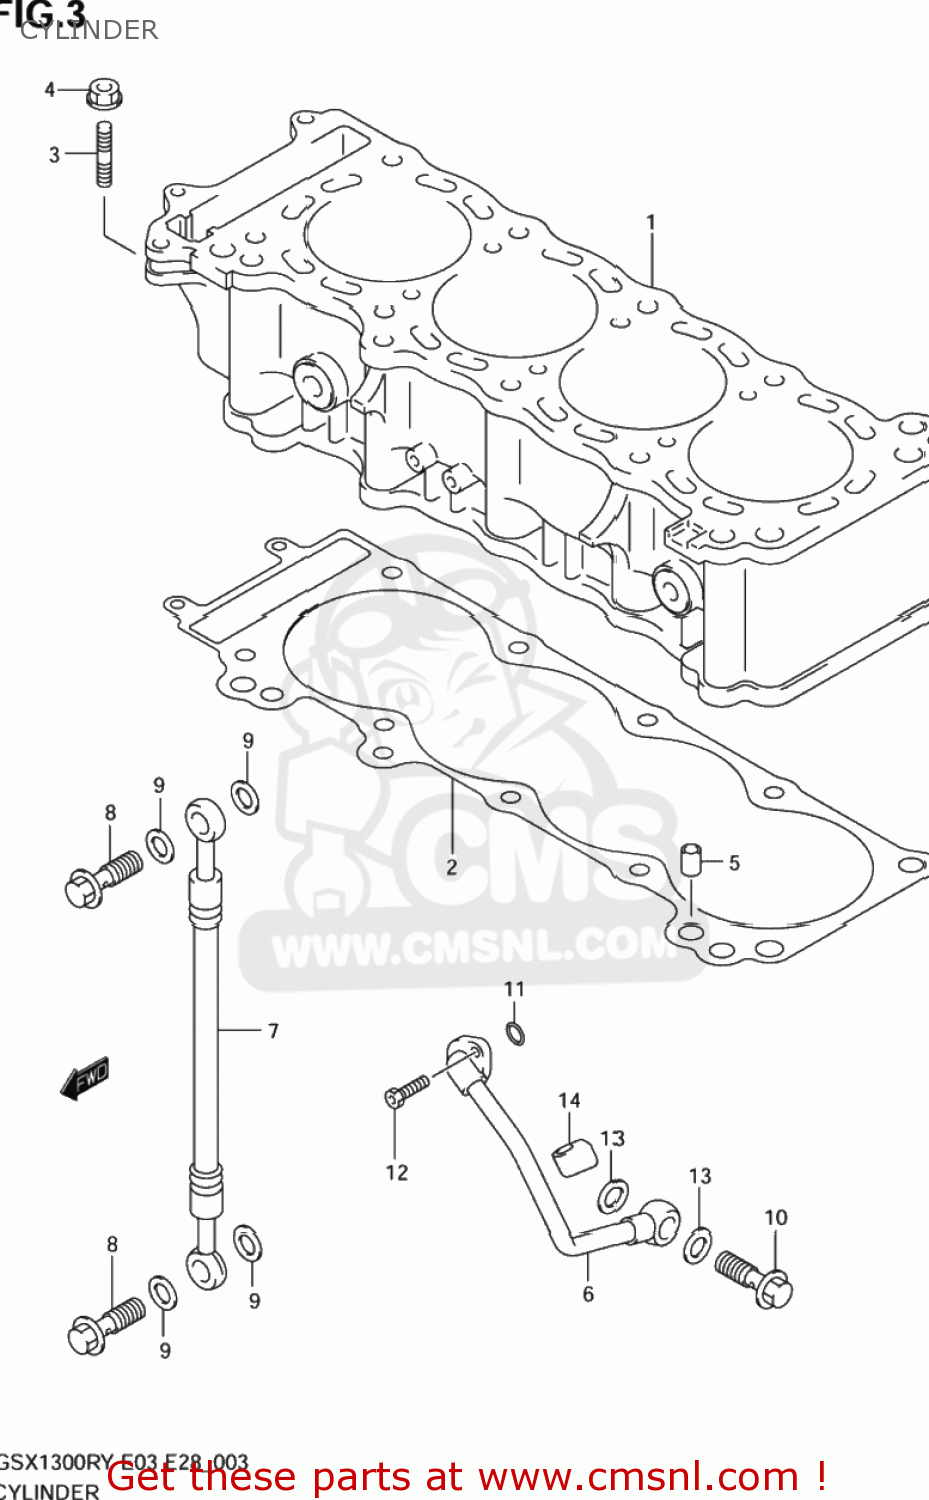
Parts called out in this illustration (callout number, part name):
1	CYLINDER
2	GASKET,CYLINDER (NAS)
3	STUD BOLT
4	NUT
5	PIN
6	PIPE,CRANKCASE OIL
7	HOSE,CYLINDER HEAD OIL
8	BOLT UNION
9	GASKET(10.1X16X1) (NAS)
10	BOLT UNION
11	O RING(D:2.4,ID:11.8)
12	BOLT(6X16)
13	GASKET(14X20X1.5) (NAS)
14	CUSHION,CRANKCASE DIL PIPE
